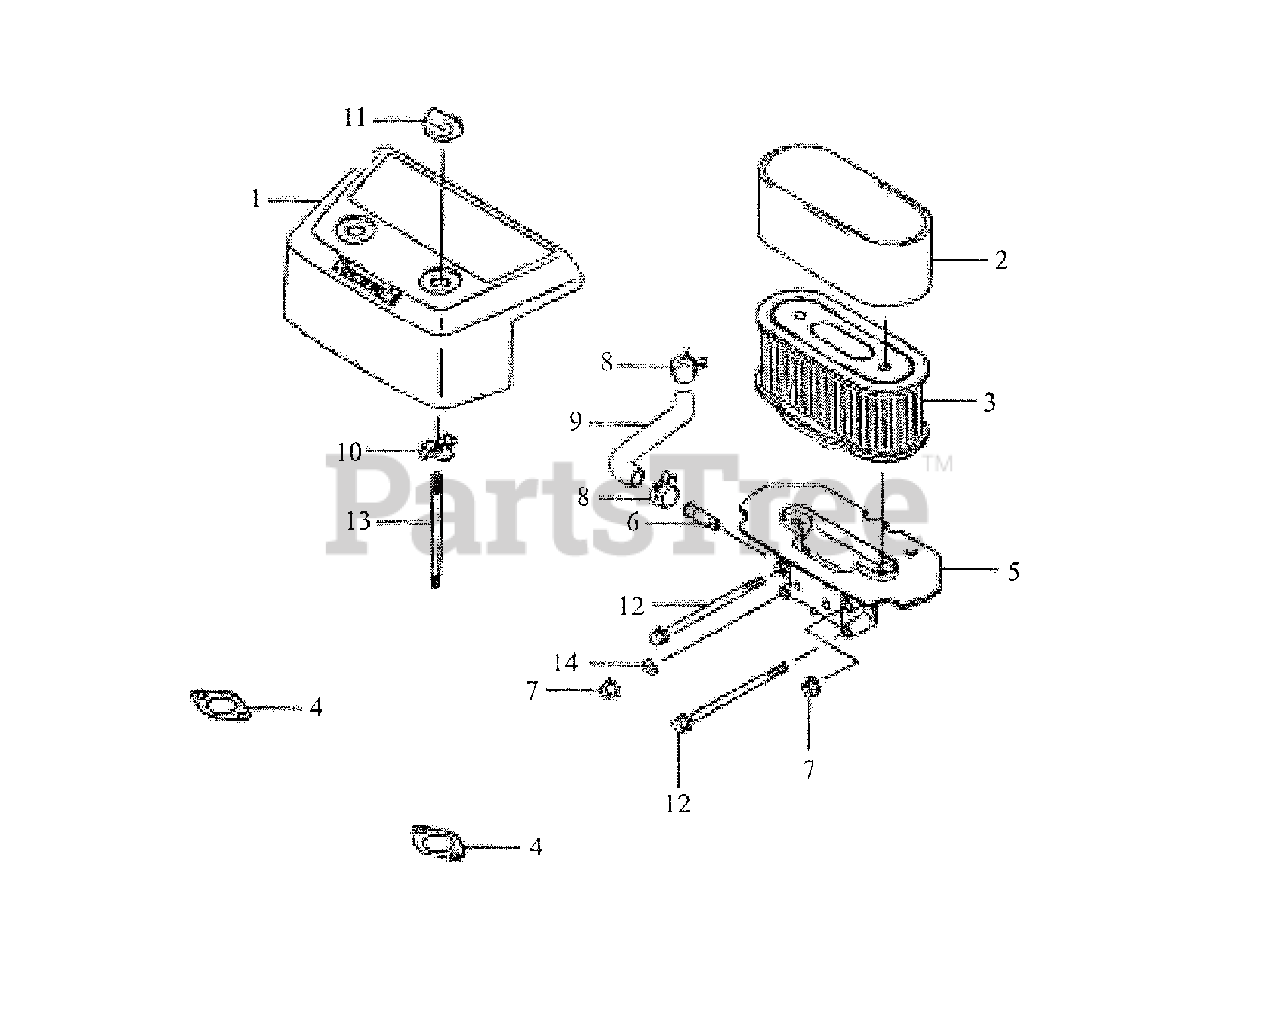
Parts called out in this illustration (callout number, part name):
1	Case-Air Cleaner
2	Element-Air Cleaner
3	Element-Air Cleaner
4	Gasket-Muffler
7	Nut
8	Clamp
11	Nut
12	Bolt-Flange
13	Bolt-Stud
14	Washer-Plain
